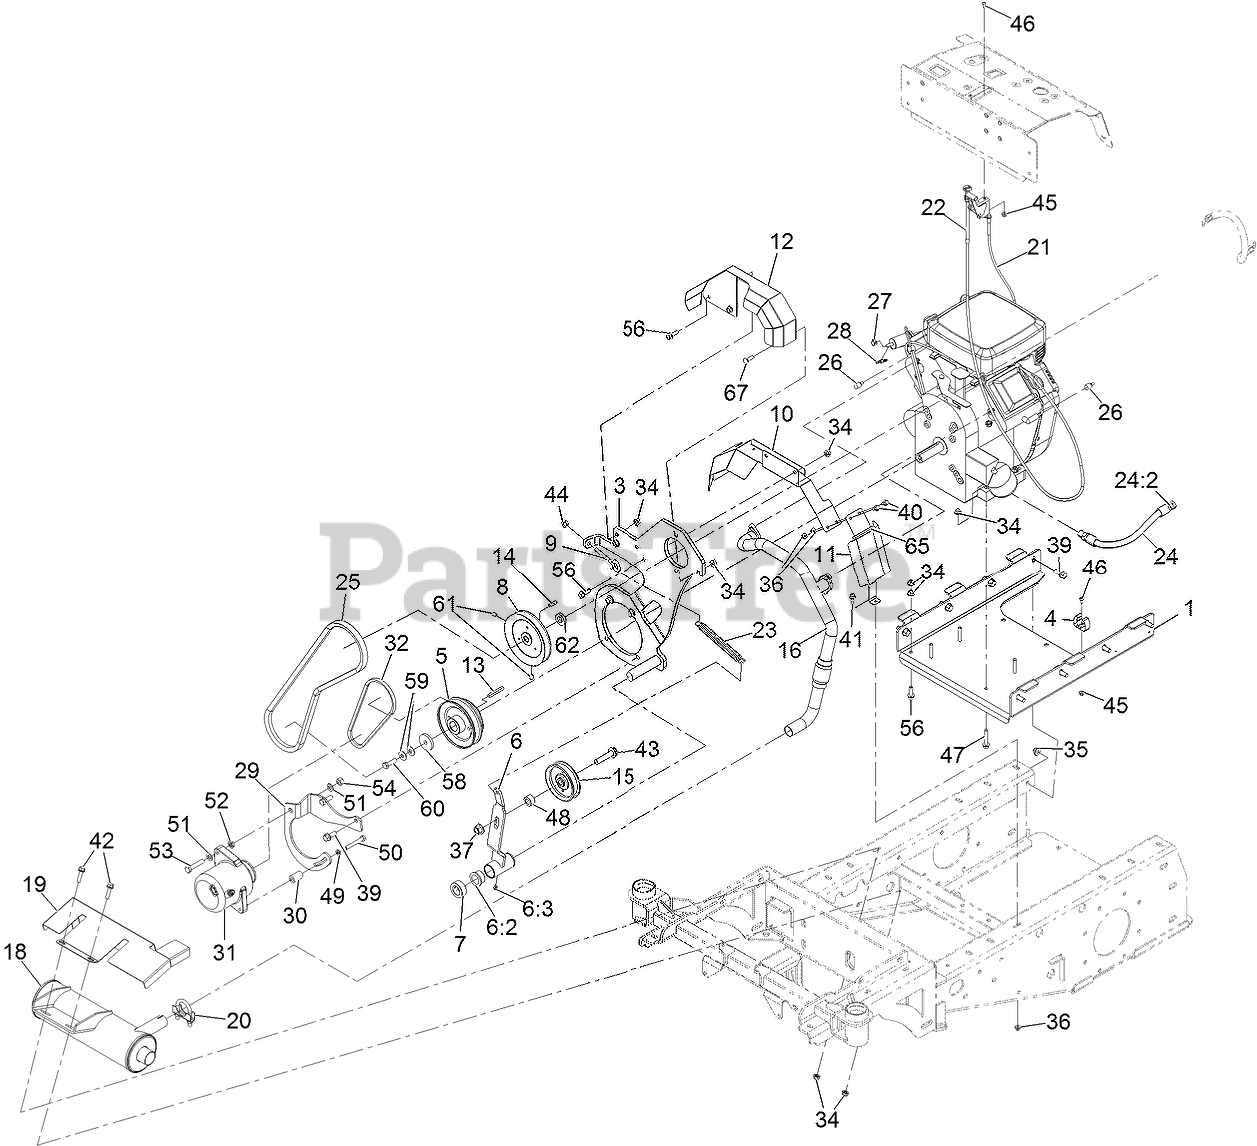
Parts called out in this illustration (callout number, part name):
1	Tray-Engine
3	Bracket-Engine, Pump [black]
4	Holder-Tool, Clip
5	Pulley-Double
6	Arm-Tension, ASM
6:2	BUSHING-FLANGE
6:3	FITTING-GREASE, ZERK
8	PULLEY-DRIVE, PUMP
9	Bolt-Eye
10	Guard, Lower Muffler
11	Guard, Lower Muffler
12	GUARD-PULLEY
15	PULLEY-IDLER, FLAT
16	MANIFOLD-EXHAUST
18	MUFFLER
19	SHIELD-HEAT, MUFFLER
20	Clamp-Muffler
21	CABLE-THROTTLE
22	CABLE-CHOKE
23	SPRING-EXTENSION
24	ASM, Oil Drain Hose W/Plug
26	Tube-Heat Shrink, 1/2
27	CLAMP-HOSE
28	Fitting-STR
29	Bracket-Alternator
30	TUBE-SUPPORT, ALTERNATOR
31	ALTERNATOR
32	Belt-V, 3L240
34	Nut-Hex Flange
35	Nut-Hex Flange
36	Nut-Hex Flange
37	Nut-Lock 1/2-13
39	SCREW-HHF
40	SCREW-HHF
41	Screw-HHF
42	SCREW-HHF
43	Screw-HHF
44	NUT-HF, NI
45	Nut-Hex Flange
46	Screw-HSBH
47	Screw-HHF
49	WASHER-LOCK
50	Screw-HH
51	Washer-Flat
52	Nut-Hex
53	Screw-HH
54	Nut-Lock, NI
56	SCREW-HHF
58	WASHER-PLAIN
59	WASHER-BELLEVILLE
60	Screw-HH
61	Setscrew-HSH
65	TIE-CABLE
67	Bolt,Carriage,5/16-18X1,ST/ST 18-8
